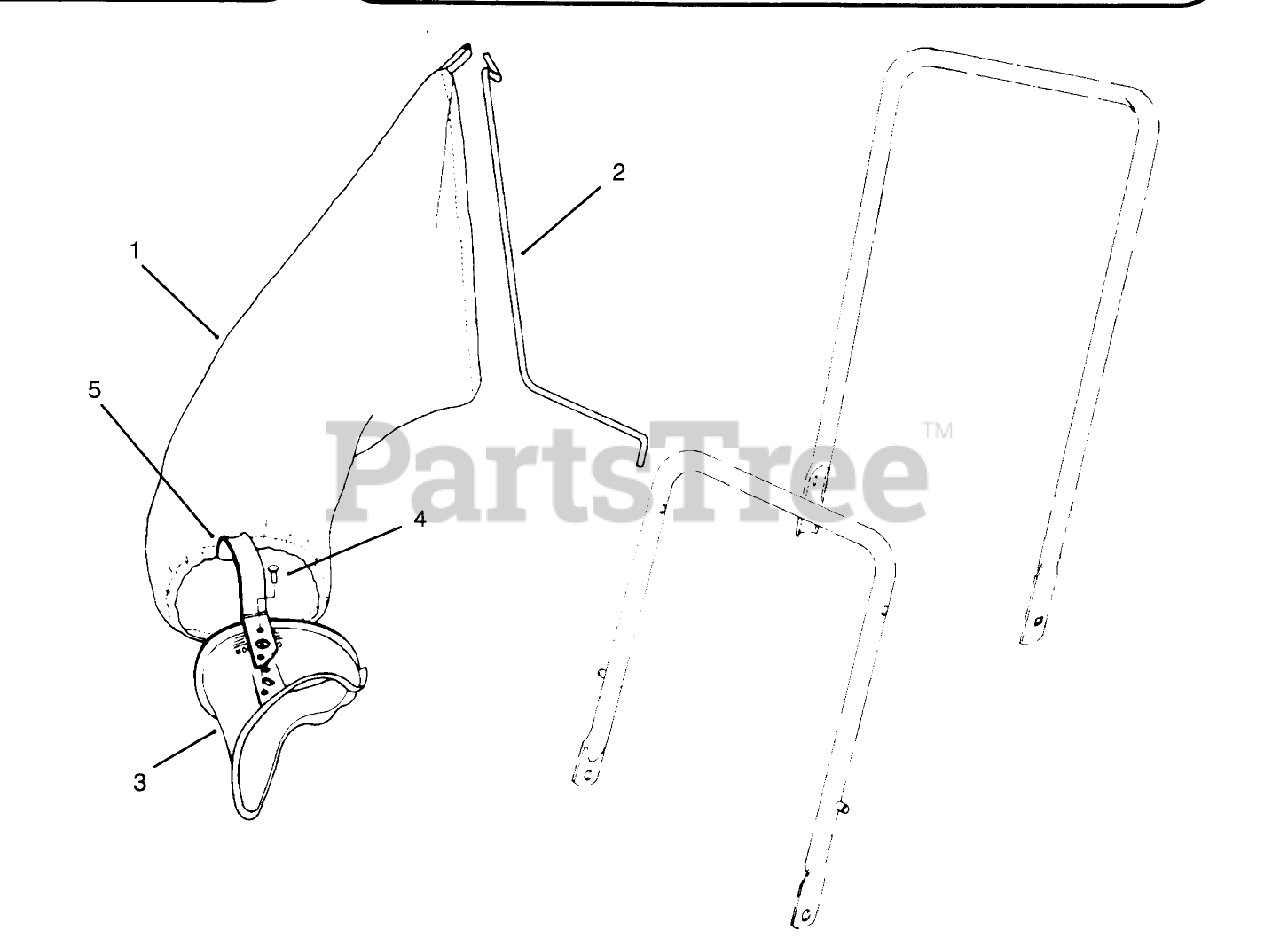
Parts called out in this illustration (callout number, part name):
1	BAG REPLACMNT44-0540
2	BAG HANGER ROD
3	Grass Chute Assembly (Incl. Ref.#4 & 5)
4	RIVET 3/16 X 7/16
5	BAG CHUTE HANDLE
